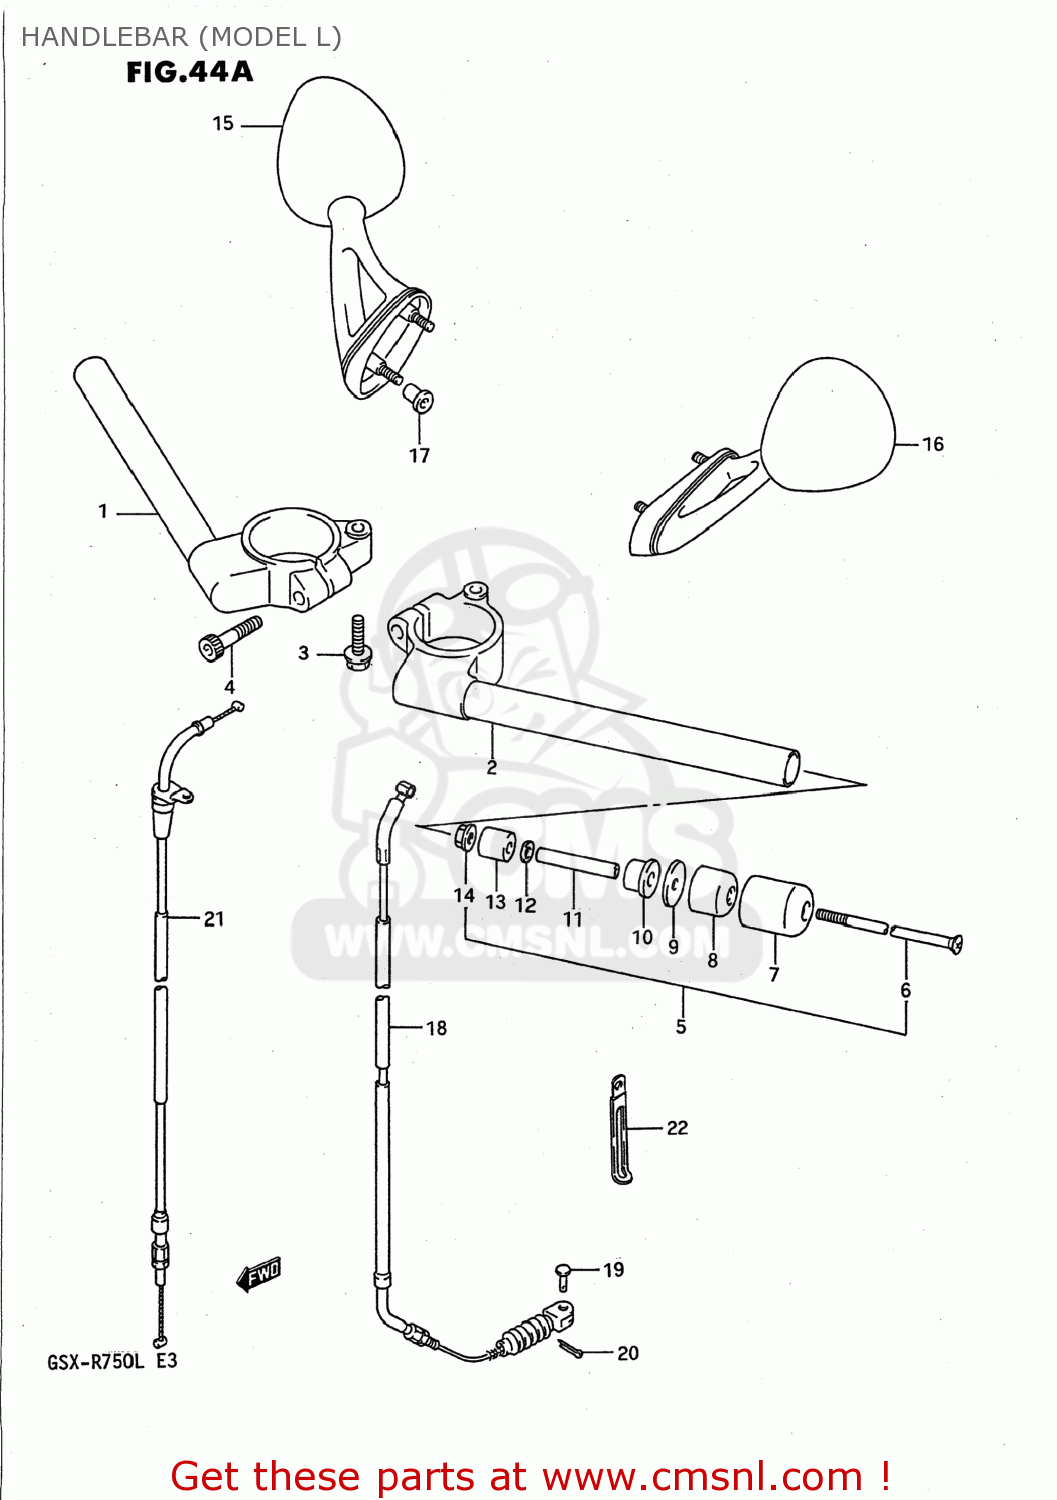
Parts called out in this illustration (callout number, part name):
1	HANDLEBAR,R
2	HANDLEBAR,L
3	BOLT
4	BOLT 8X35
5	BALANCER SET,HANDLEBAR
6	SCREW(6X127)
7	CAP,BALANCER
8	BALANCER,HANDLEBAR
9	SPACER,BALANCER
10	EXPANDER,HANDLE BALANCER
11	SPACER,EXPANDER
12	WASHER
13	EXPANDER,HANDLE BALANCER
14	NUT
15	MIRROR ASSEMBLY,REAR VIEW
16	MIRROR ASSEMBLY,REAR VIEW
17	NUT,RR VIEW MIRROR
18	CABLE ASSY,CLUTCH
19	PIN(L:15)
20	PIN
21	CABLE ASSY,THROTTLE
22	CLAMP
